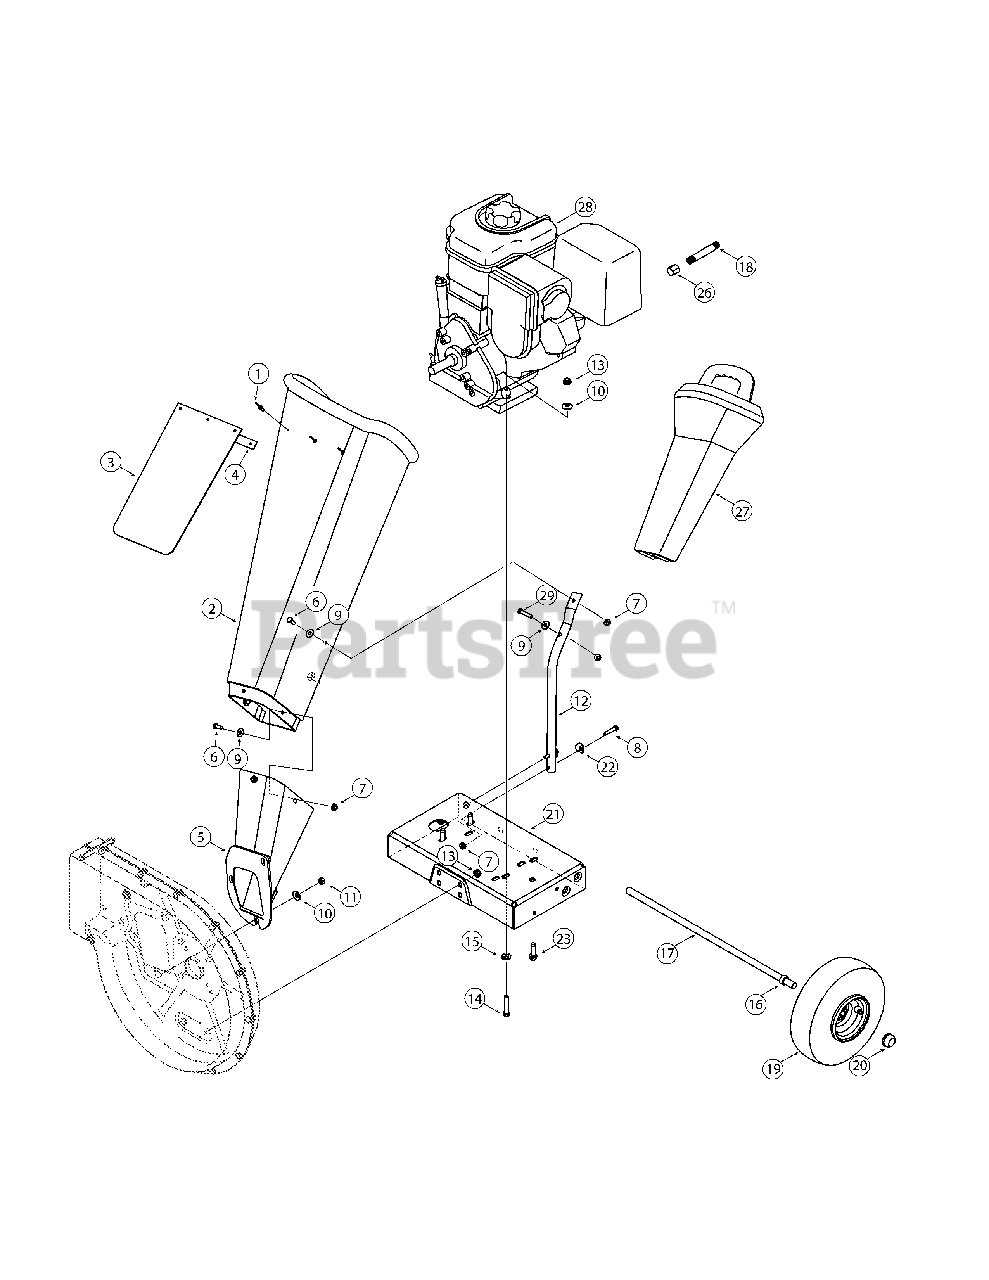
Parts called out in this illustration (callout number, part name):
1	Pop Rivet
2	Chipper Shredder Chute
3	Chute Flap
4	Chute Flap Strip
5	Chipper Chute Assembly
6	Hex Cap Screw 1/4 -20 x.620
7	Hex Lock Nut 1/4-20
8	Hex Cap Screw 1/4-20 x 1.25
9	Flat Washer .28 ID x .74 OD
10	Bell Washer .340 ID x .872 OD
11	Hex Nut 5/16-18
12	Support Brace
13	Hex Lock Nut 5/16-18
14	Hex Cap Screw 5/16-18 x 1.75
15	Bell Washer 5/16 x 1.0
16	Spacer
17	Axle Assembly
18	Pipe, Oil Drain
19	Wheel Complete, 10.0 x 4.0 Gray
20	Push Cap
22	Washer,.320 ID x.93 OD
23	Screw, 3/8-16 x 1.250
26	Oil Drain End Cap
27	Tamper
28	Replacement Engine 20T212-0835-F1
29	Hex Screw, 1/4-20 x 1.25
